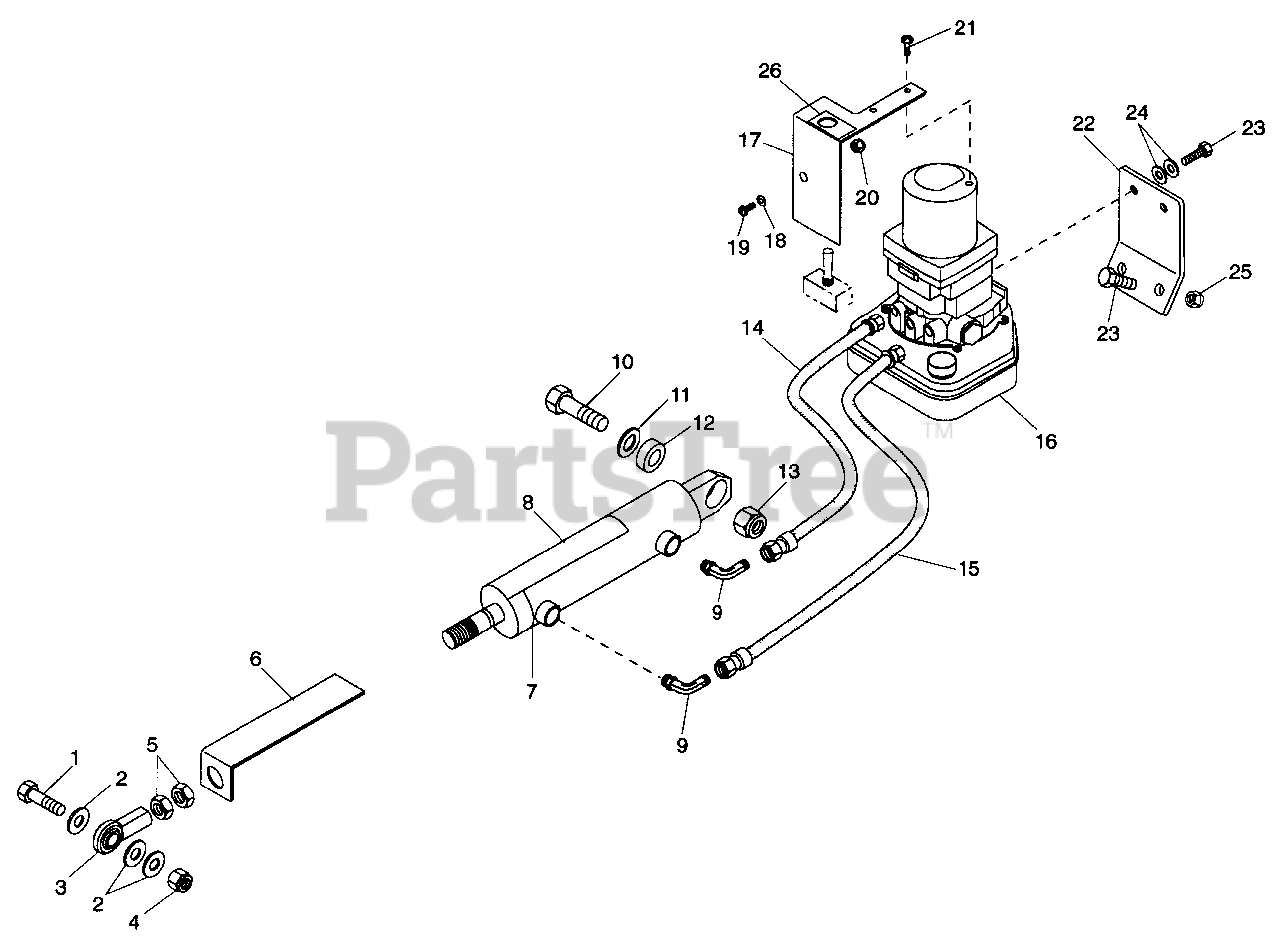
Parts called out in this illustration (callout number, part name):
1	BLT-HEX .625-11 X 2.50
2	WSHR-FL-STL .625 X 1.375 X .109
3	ROD END
4	NUT-LK-NYL .625-11
5	NUT-JAM .625-18
6	STRAP-HEIGHT OF CUT INDICATOR
7	CYL, HYD LIFT
8	DECAL-HEIGHT OF CUT
9	ADPT 2503-4-4
10	BLT-HEX .50-13 X 2.00
11	WSHR-FL-STL .531 X 1.250 X .100
12	BUSHING, HYD CYL MTG
13	NUT-LK-NYL .50-13
14	ASM, HOSE PUMP TO CYL
15	ASM, HOSE PUMP TO CYL
16	PUMP, ELECTRIC-HYDRAULIC
17	SWITCH PLATE, LIFT PUMP
18	WSHR-FL-STL .281 X .625 X .065
19	SCR-MCH .25-20 PAN HD
20	NUT-LK-NYL .250-20 PL
21	SCR-TAP 12-14 X .50 CRPH PL
22	BRKT, HYD PUMP MTG
23	BLT-HEX .38-16 X .75 PL
24	WSHR-FL-STL .406 X .812 X .065
25	NUT-LK-NYL .375-16 W/INSR
26	DECAL, CUTTING HT ADJ
